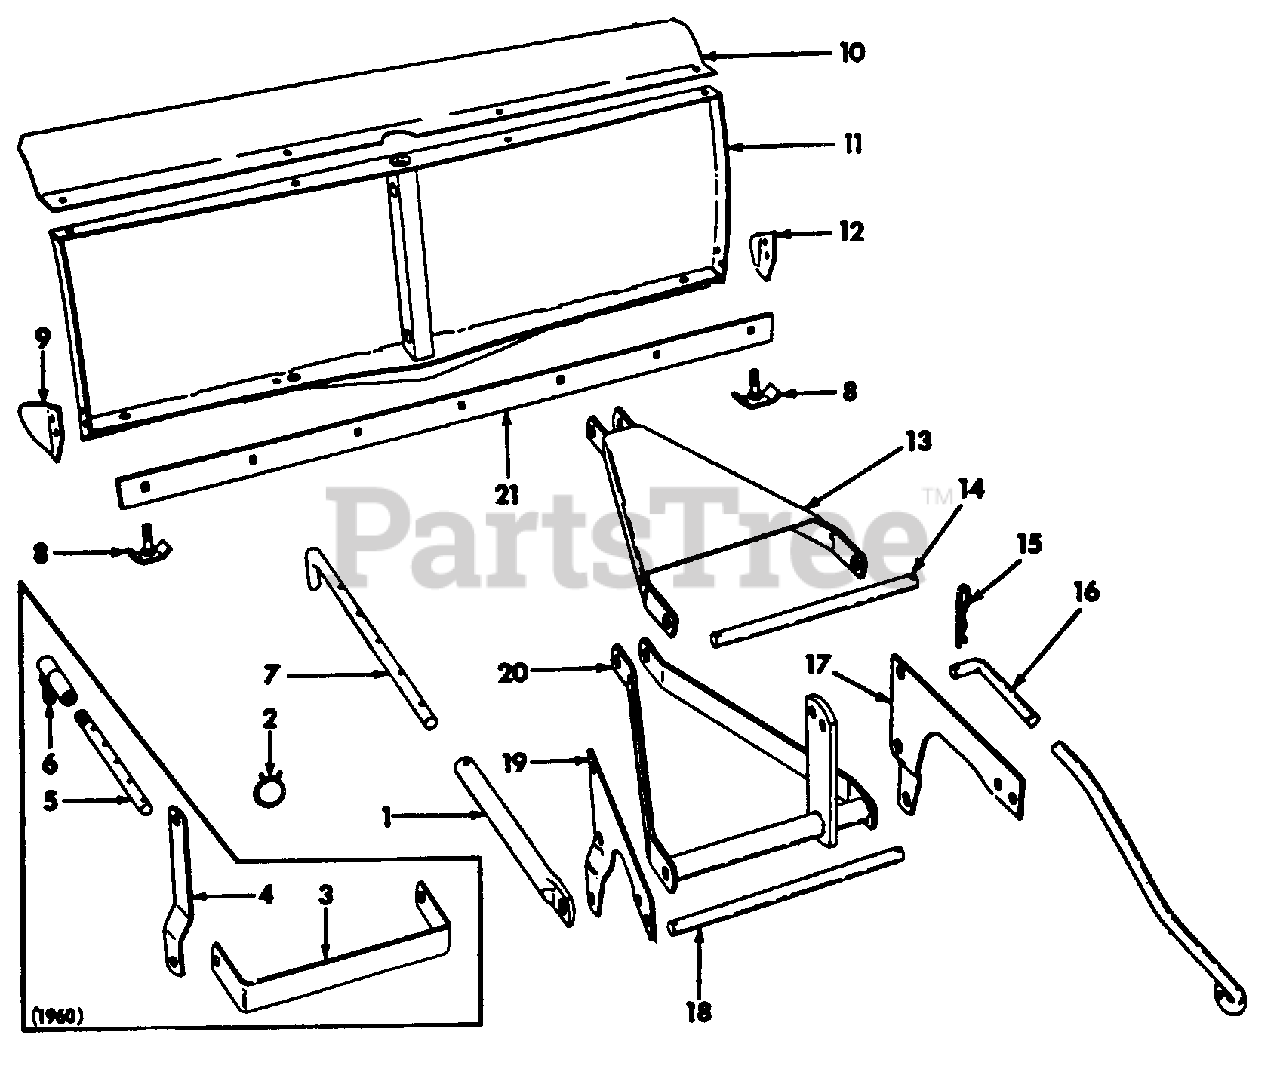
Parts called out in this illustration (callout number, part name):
1	Tube, Adjusting
2	Clamp, Hose -for Cot. Pin Storage
3	Brace, Tractor Frame - Order Ref. Nos. 17 & 19
4	Bar, Mounting, Order Ref No. 19
5	Rod, Adjusting -1960
6	Joint, Ball -1960
7	Rod, Adjusting -1961-
8	Shoe, Skid -1960- Order Shoe 465 376 R11 and Two Nuts 120 238
9	Trip, Blade LH
10	Deflector w/RH Trip, Snow -1961
12	Trip Blade RH -1961
13	Link Assy, Upper
14	Pin, Rear Pivot
15	Pin, Quick Attachable Cotter
17	Plate, Mounting RH -1961
18	Pin, Rear Lower
19	Plate, Mounting LH -1961
20	Link Assy, Lower
21	Edge, Cutting
IH-16-897-R1	Bolt, 5/16 X 3/4 C-Z Sq-Nk Crg
